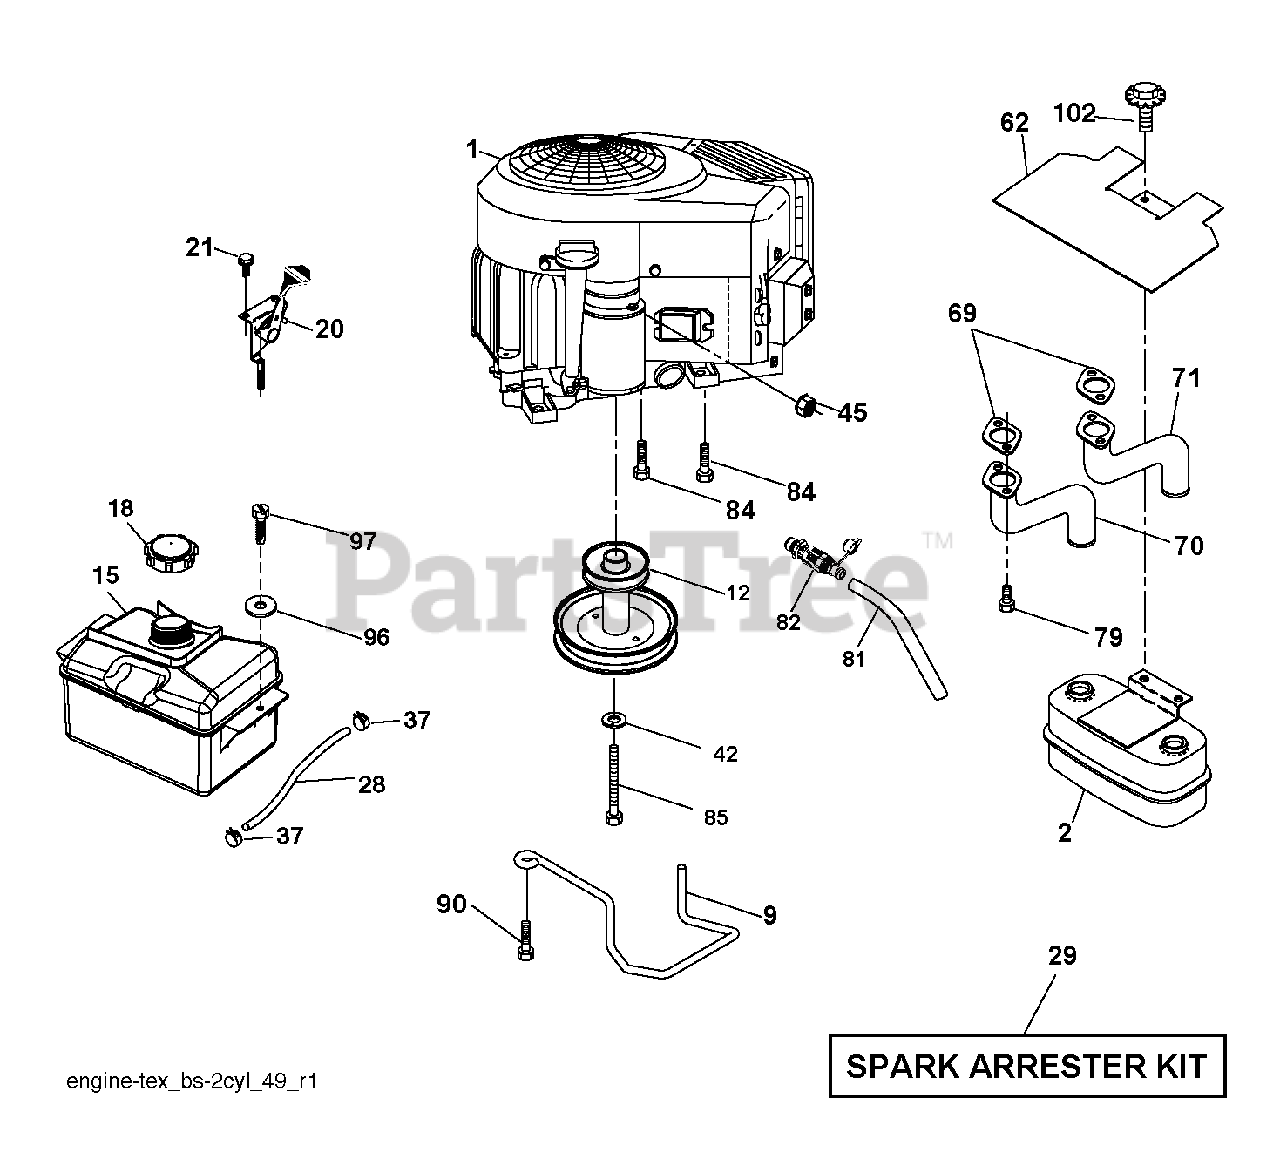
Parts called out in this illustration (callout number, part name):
2	MUFFLER.ASM.TWN.EXTNDED.DFLCTR
9	KEEPER.BELT.ENGINE
12	PULLEY.ENGINE.5.0.PD
15	TANK.ASSEMBL.2.5GAL.NON-EPA
18	CAP ASM.FUEL.2.25"FR.
20	THROTTLE.COBRA.38"READSTART.BK
21	SCREW.#10 X 0.750.BOS
28	LINE.FUEL.20
29	KIT.SPARK ARRESTOR 794945 B&S
37	HOSE CLAMP
42	LOCKWASHER
45	NUT
62	SHIELD.HEAT.MUFFLER
69	GASKET.MUFFLER
70	EXHAUST.TUBE.LH.BS/TWIN
71	EXHAUST.TUBE.RH.B&S.TWIN.INTEK
79	SCREW.SOCKET.HEAD.5/16-18
81	TUBE, DRAIN OIL ASM.
82	VALUE.OIL.DRAIN
84	SCREW.3/8-16
85	BOLT HEX 7/16-20X4-1/4"
90	SCREW 3/8-16X1
97	SCREW HEXWSHR 1/4-20X3/4
102	SCREW
